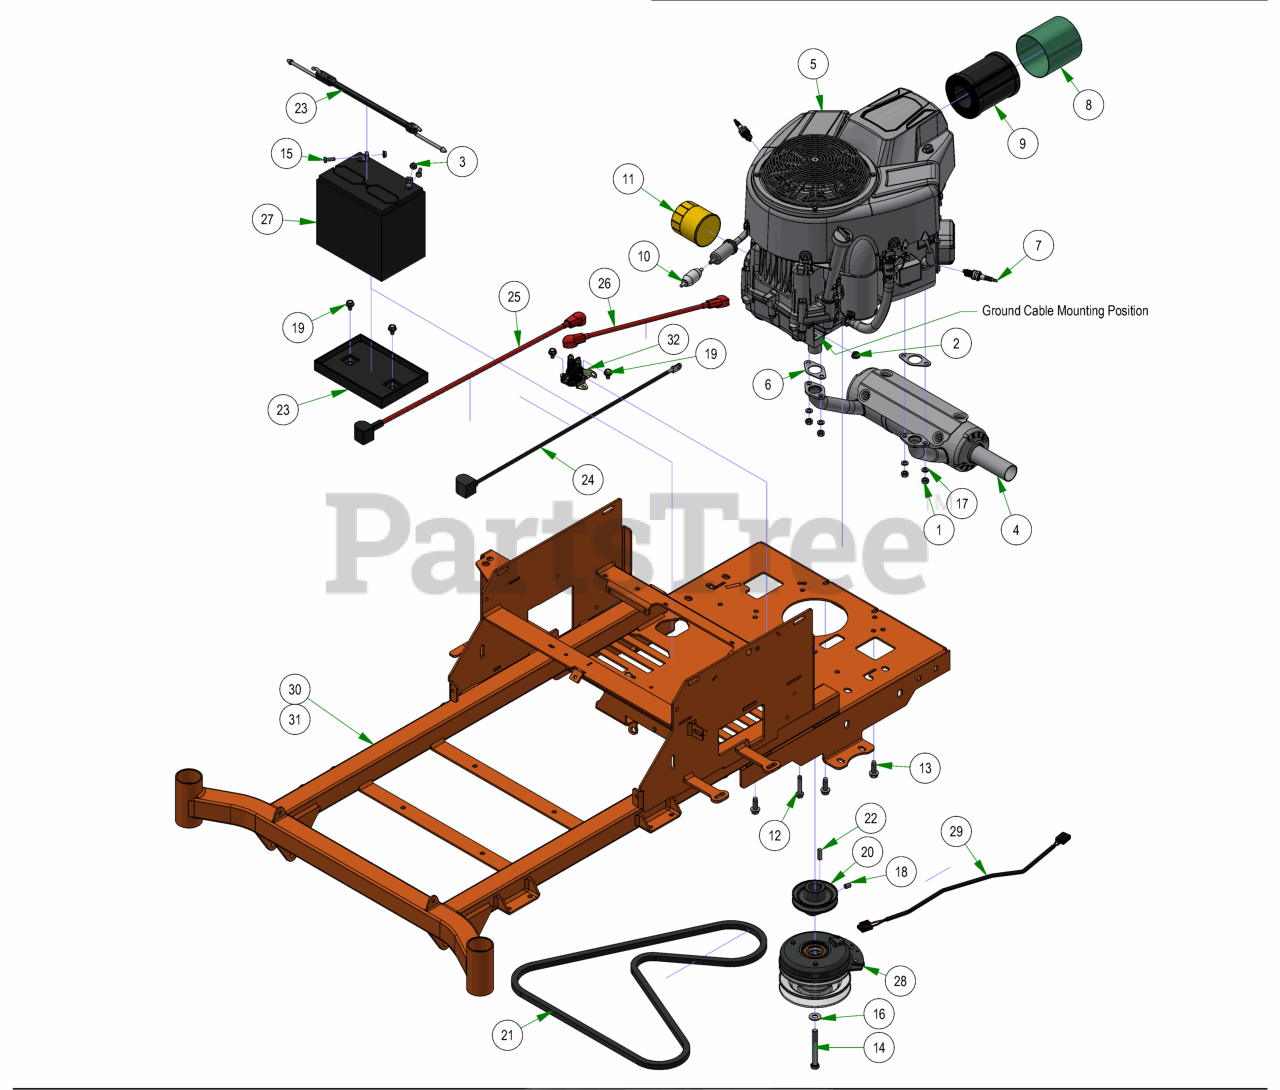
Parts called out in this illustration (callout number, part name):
1	M8-1.25 DIN 934 HEX NUT (CL.8) ZINC
2	5/16-18 Gr5 Distorted-Thread Flange Locknut
3	1/4-20 HEX SERRATED FLANGE NUT HARD/ZINC
4	2017 Compact Outlaw Exhaust 810 Vanguard
5	Vanguard 25hp CXI with out Oil Filter ZT Elite
6	Exhaust Gasket
7	Spark Plug
8	pre-Cleaner for Vanguard CXI Engine
9	Air Filter for Vanguard CXI Engine
10	Universal Inline Fuel Filter
11	Oil Filter
12	5/16-18x1-3/4 Gr5 Hex Flange Screw Zinc Clear
13	3/8-16 X 1-1/8 HEX WASHER UNSLOT SERRATED (TRI-LOB) TRS ZINC YELLOW
14	7/16-20 x 3 1/2" Hex Bolt GR8 W/ Patch
15	1/4-20 X 3/4 HEX CAP SCREW (GR.5) ZINC
16	3/8 FLAT WASHER USS (1" OD) ZINC
17	5/16 SPLIT LOCKWASHER ZINC
18	3/8-16 X 1/2 SOCKET SET SCREW (CUP PT) PLAIN
19	5/16-18 X 1/2 HWH unslot (F) tcs zinc
20	3-3/4" Motor Pulley
22	1/4 X 1 SQ MACHINERY KEY 1018 STL PLN
23	2023 Battery Hold Down Assembly
24	24 inch Black Cable – MZ/ZT
25	24" Red Battery Cable
26	14" Red Battery Cable
27	SP-35 Battery
28	105 Ft Lb. Clutch - 1" Shaft
29	Clutch Pigtail
30	2025 MZ 42-48 Frame
31	2025 MZ-Avenger 54-60 Frame
